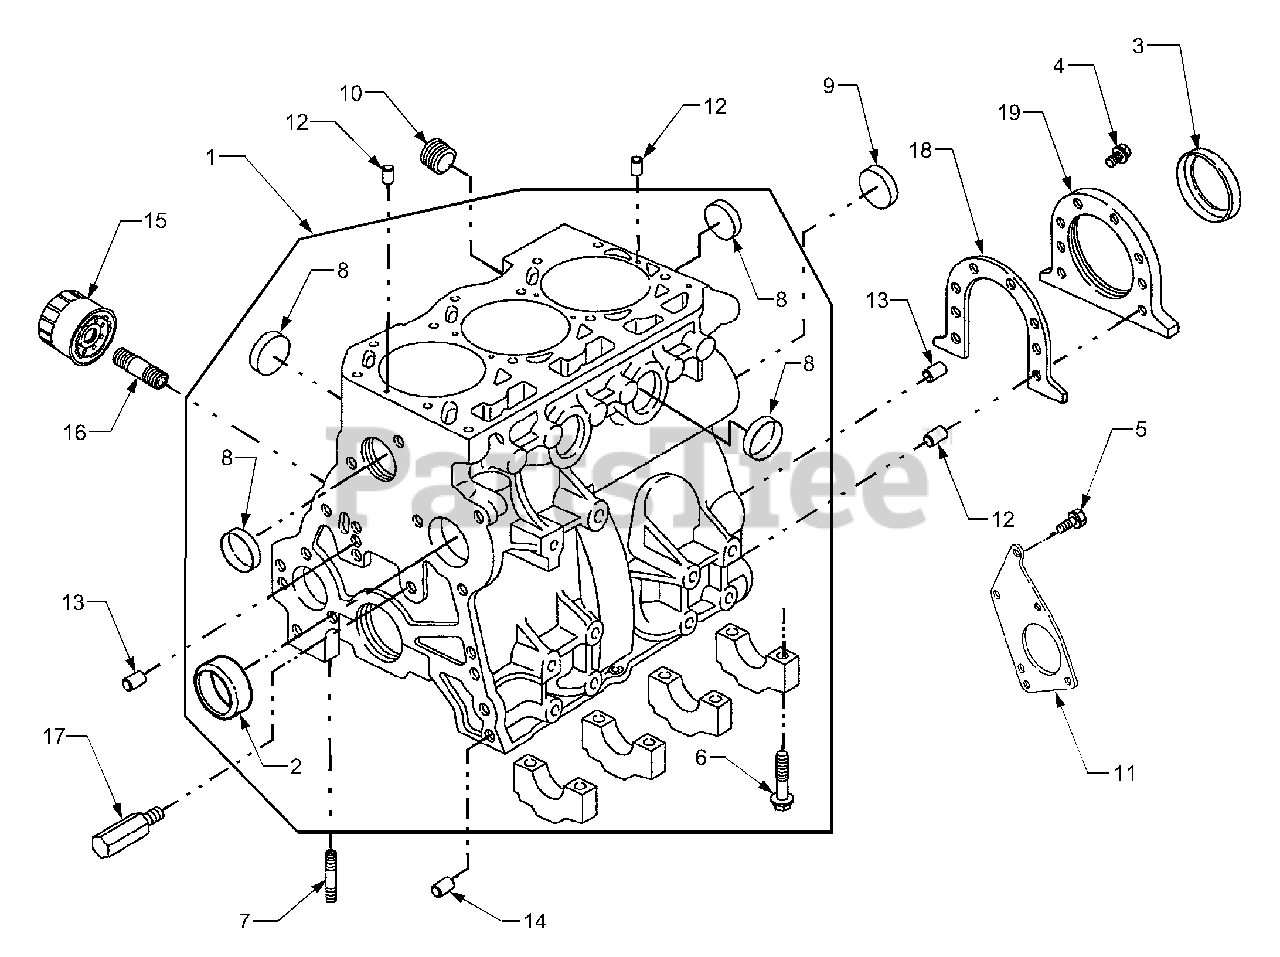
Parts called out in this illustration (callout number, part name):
1	Cylinder Assembly
2	Bushing
3	Seal, Oil
4	Screw, Hex, 6mm
5	Screw, Hex, 10mm
6	Screw, Hex, 10mm
7	Stud, Metric
8	Plug, Welch
9	Plug, Welch Camshaft
10	Plug, Cylinder Block
11	Bracket, Mounting
12	Pin, Locating
13	Pin, Locating
14	Pin, Locating
15	Filter, Oil
16	Adapter, Oil Filter
17	Nozzle, Oil
18	Gasket, Retainer
19	Seal, Retainer
